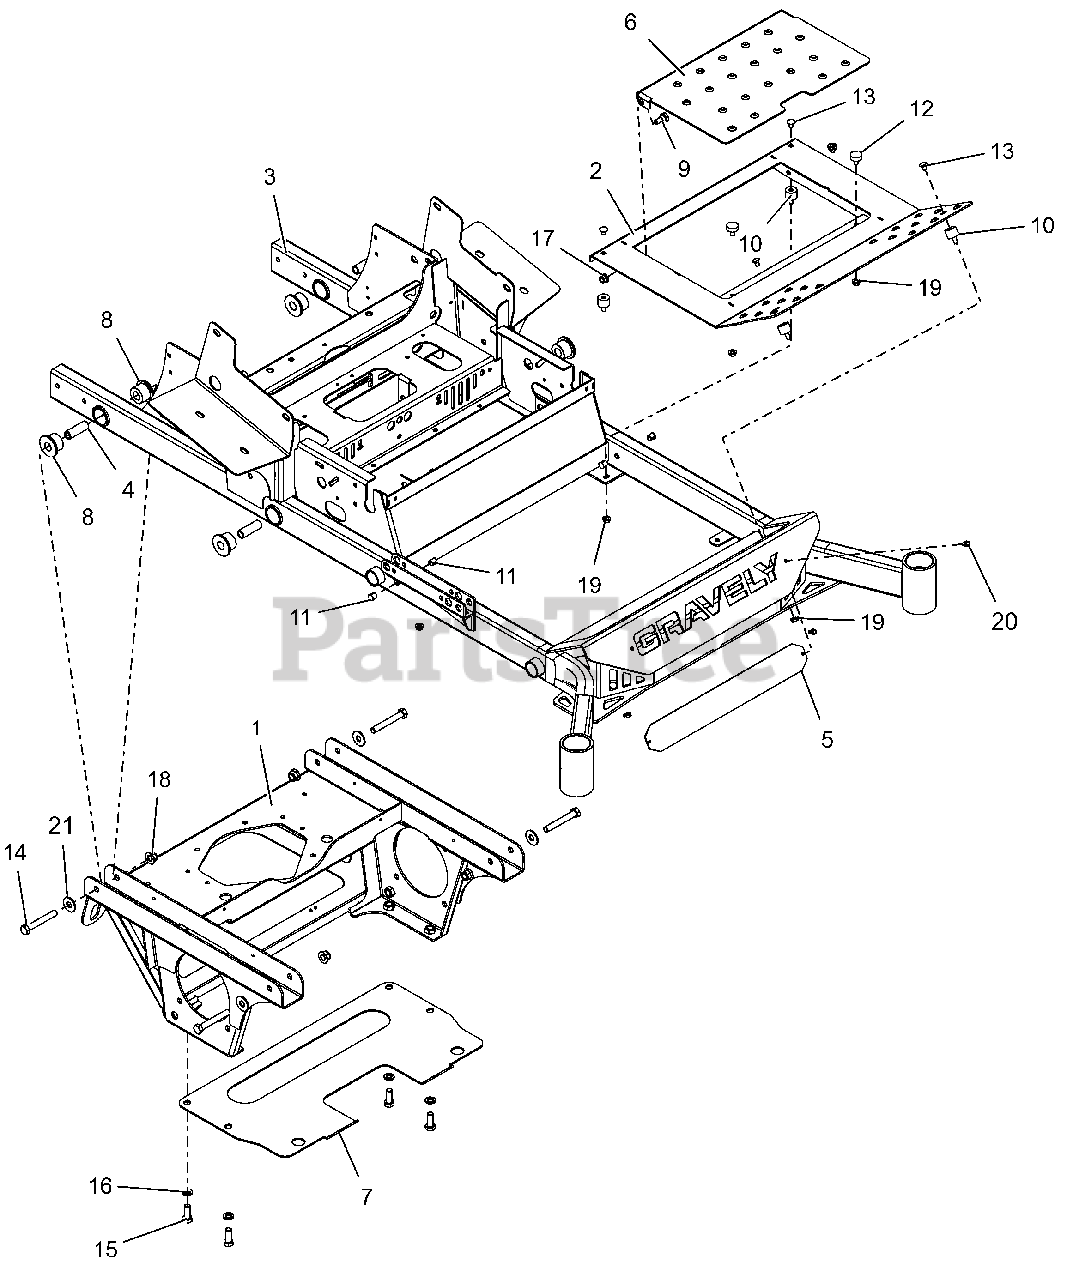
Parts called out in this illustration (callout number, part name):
1	PT200/400 AXLE/ENG FRM WMT-RED
2	FOOTPLATE WLDMT W/SAFETY DECAL
3	52-60"PT200/400 FRAME W/DECALS
4	BSHG-SLV .50X.75X2.23
5	BUMPER LOGO BACKING PLATE -BLK
6	INSPECTION PANEL W/SAFTY DECAL
7	PLATE-TRANSMISSION SKID
8	BSHG-FLG .75X1.51X1.13X2.0 URE
9	BLT,SHLDR EP .38-16X.30 HEX YZ
10	BUMPER,STUD MNTD W/FEMALE INSR
11	PLUG, HOLE .50
12	BUMPER, RUBBER
13	@BLT-RDHDSQNK .31-18X.50 G5YZ
14	@BLT-HEX .50-13X3.50 GR5 YWZC
15	@BLT-HEX .50-13X1.25 GR5 YWZC
16	@WSHR-LK .50X.125 REG YWZC
17	@NUT-LK-NYL-FLG .38-16 YWZC
18	@NUT-LK-NYL-FLG .50-13 YWZC
19	@NUT-SPNLK-FLG .312-18 YWZC
20	SCR-TAP .25-20X.50 HWH TR YWZ
21	@WSHR-FL-STL.563X1.38X.109YWZC
